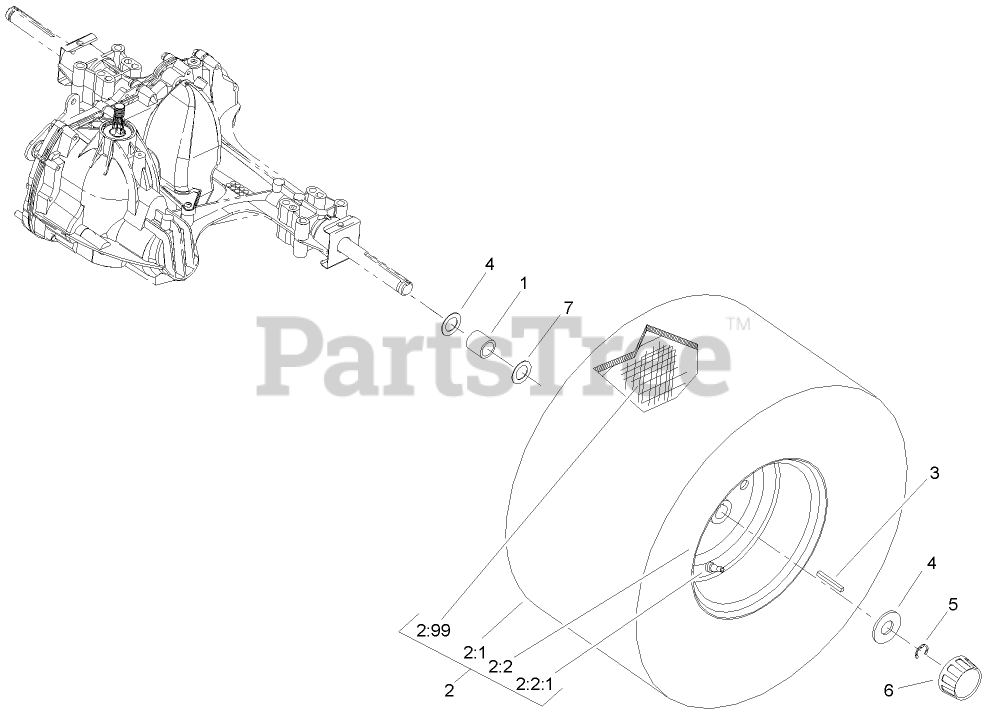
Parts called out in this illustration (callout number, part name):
1	SPACER-WHEEL
2	Loose Parts Package
2:99	TUBE-INNER
3	KEY-SQUARE
4	WASHER-PLAIN
5	E-RING
6	CAP-HUB
7	WASHER-THRUST
